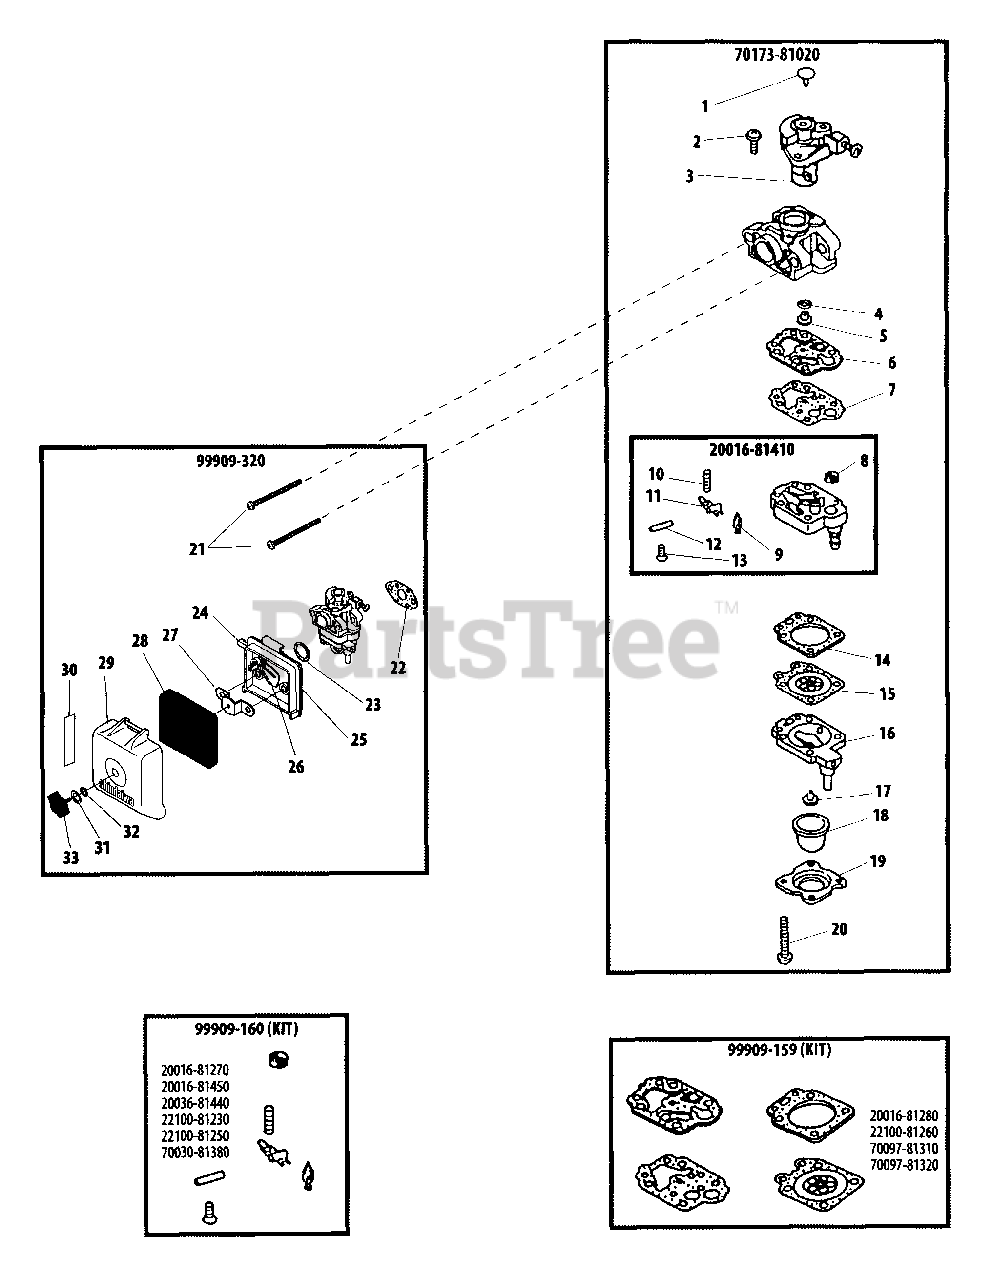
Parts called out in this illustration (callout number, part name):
1	PLUG, WELCH
2	SCREW
3	THROTTLE VALVE ASSY
4	O-RING
5	JET, MAIN - 38
6	GASKET, PUMP
7	DIAPHRAGM, PUMP
8	STRAINER
9	VALVE, INLET NEEDLE
10	SPRING, METERING LEVER
11	LEVER, METERING
12	PIN, METERING LEVER
13	SCREW, METERING LEVER PIN
14	GASKET, METERING
15	DIAPHRAGM, METERING
16	BASE, PURGE
17	VALVE, CHECK
18	BULB, PURGE
19	RETAINER, PURGE BULB
20	SCREW, PUMP COVER
21	SCREW - 5X67
22	GASKET
23	O-RING - 15
24	LEVER, CHOKE
25	CASE, AIR FILTER
26	PLATE, CHOKE
27	PLATE, PREVENT
28	FILTER, AIR - FOAM
29	COVER, AIR FILTER
30	LABEL - CHOKE
31	WASHER - CONICAL
32	O-RING
33	THUMBSCREW
20016-81410	PUMP BODY ASSY
70173-81020	CARBURETOR
99909-159	DIAPHRAGM/GASKET KIT
99909-160	REPAIR KIT
99909-320	AIR FILTER ASSY
